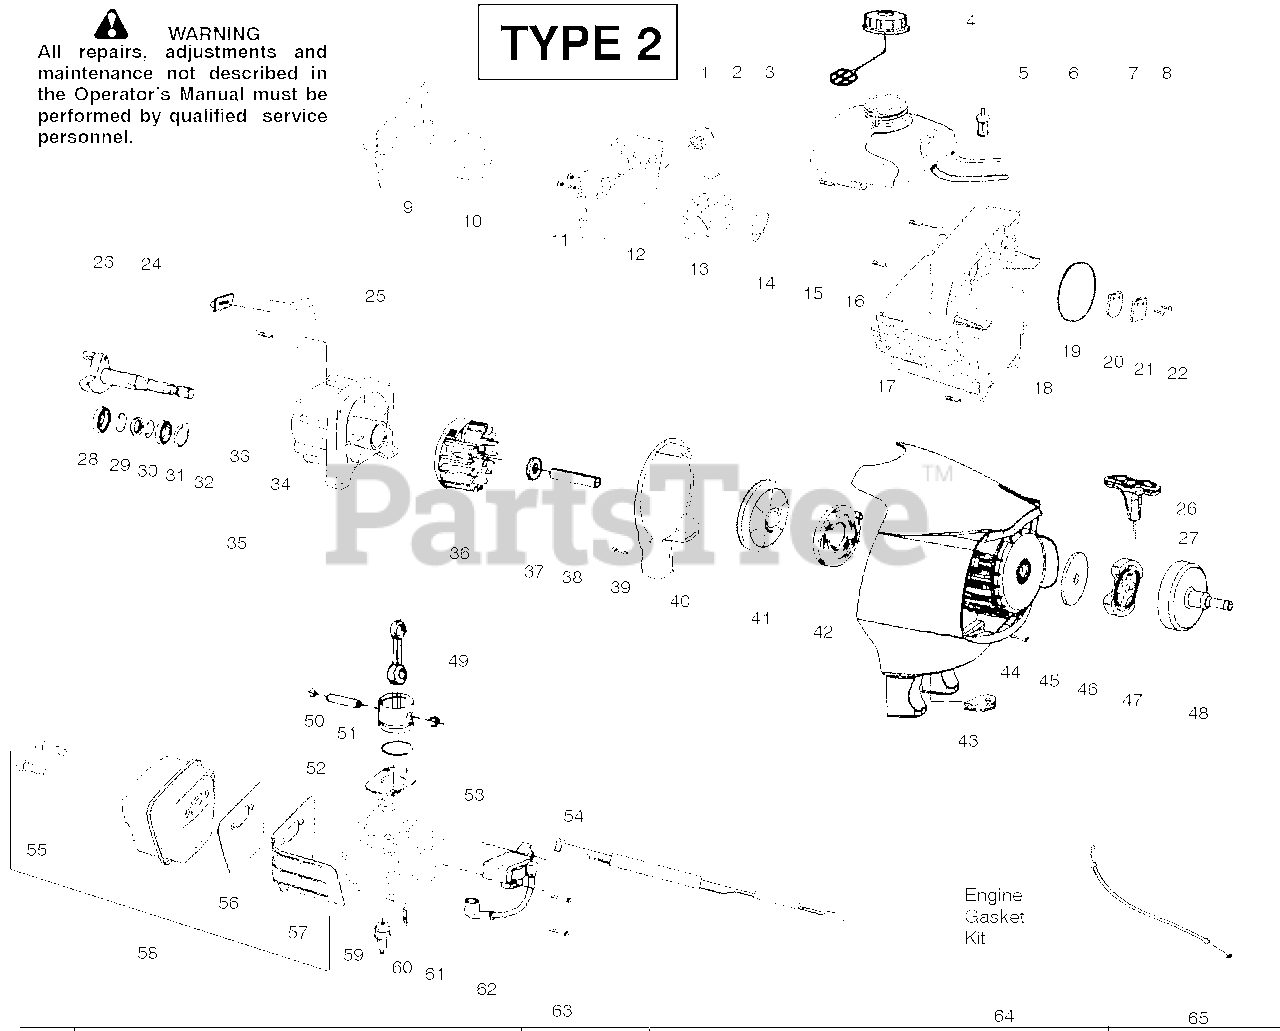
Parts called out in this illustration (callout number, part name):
2	Bulb-Purge
2	Kit-Choke Lever
3	Screw-tank
4	Cap-Fuel w/ret.
5	Assy-Fuel pickup
6	Kit-Fuel line
7	Kit-Fuel/Purge line
9	Cover-Air box
10	Filter-Air
11	Screw-Carb.
13	Kit-Carb assy. (C1U-W32)
14	Seal-Carb.(kit)
15	Assy-Fuel Tank
16	Screw-Crankcase
17	Screw-Shroud
18	Assy-Rear Shroud
19	O-ring-Shroud (kit)
20	Valve-Reed
21	Stop-Reed
22	Screw-Reed stop
23	Screw-Retainer
24	Isolator-Tank
25	Ret.-Tank
26	Handle-Starter
27	Kit-Rope
28	Bearing-Inner
29	Retainer
31	Bearing-Outer
32	Ret.-Crankshaft
33	Assy-Crankshaft
34	Assy-Crankcase
35	Assy-C'case/C'shaft
36	Assy-Flywheel
39	Screw-Baffle
40	Plate-Baffle
41	Kit-Pulley
42	Spring-Starter
44	Screw-F/hsg.
45	Assy-Fan Housing
46	Washer-Clutch
47	Assy-Clutch
48	Assy-Drum/Adapter
49	Assy-Conn. Rod
50	Ret.-Piston pin
51	Ring-Piston
52	Kit-Piston
53	Gasket-Cylinder(kit)
54	Assy-Leadwire
55	Bolt-Muffler 1/4"-20
56	Gasket-Muffler (kit)
58	Kit-Muffler
59	Cylinder
60	Plug-Spark(RCJ-6Y)
61	Bolt-Cyl. 1/4"-20
62	Module-Ignition
63	Screw-Module
64	Kit-Gasket/Seal
65	Assy-Throttle cable
